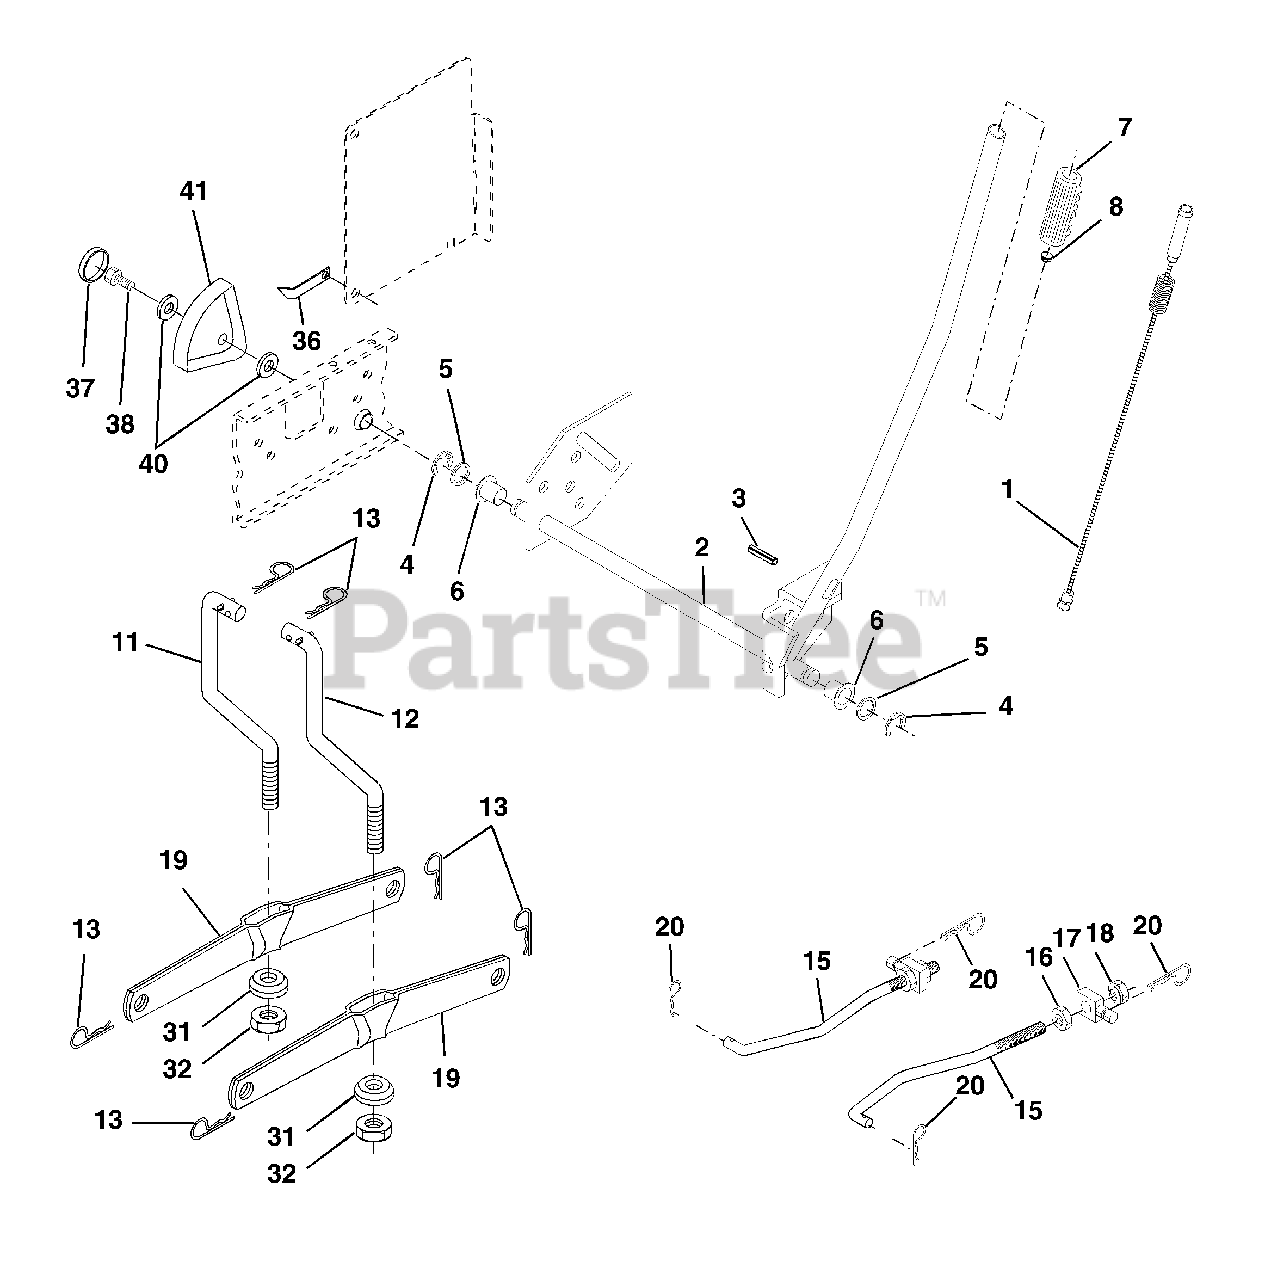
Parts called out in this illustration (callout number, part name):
1	Wire Asm Inner/Sprg W/plunger LT
2	Shaft Asm Lift RH w/Inf
3	Pin Groove 1 500 Zinc
4	E Ring #5133-62
5	Washer 21/32 X 1 X 21 Ga
6	Bearing Nylon Blk 629 Id
7	Grip Handle
8	Button Plunger
11	Link Lift LH Fixed Length
12	Link Lift RH Fixed Length
13	Retainer Spring
15	Link Front
16	Nut Jam Hex 1/2-13 Unc
17	Trunnion
18	Nut Lock W/Wsh 1/2-13 Unc
19	Arm Suspension Rear
20	Retainer Spring
31	Bearing Pvt Lift
32	Nut Crownlock 3/8 - 24
36	Pointer Height Indicator
37	Plug Hole Blk. 1.485/1.515 Dia.
38	Screw 5/16-18 x 1
40	Washer 11/32 x 1-1/210 Ga.
41	Indicator Height STLT
